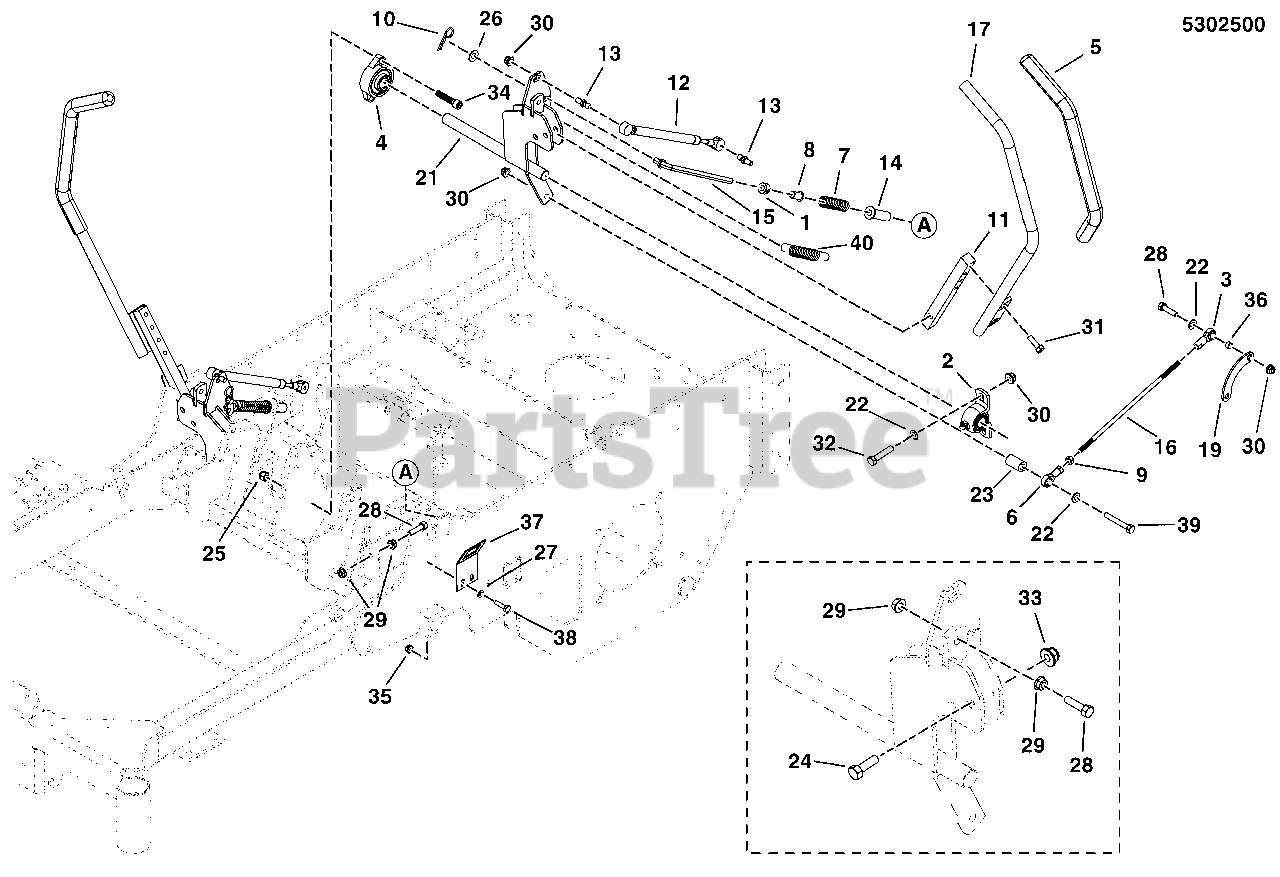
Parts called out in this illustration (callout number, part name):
1	COLLAR, 3/8" Set
2	BEARING, 3/4" PILLOW BLOCK
3	BALL JOINT 5/16-24 RH FEMALE STAMPED STL
4	BEARING, FLANGE
5	GRIP, FOAM, 3/4" ID, 16"" LONG
6	BALL JOINT 5/16-24 LH FEMALE STAMPED STL
7	SPRING, REVERSE RETURN
8	BUSHING, FLANGE 3/8ID X 7/8 LONG
9	NUT, Hex, 5/16-24
10	3/32 X 1-5/8 HAIR PIN CLIP
11	MOUNT, CONTROL ARM - BLK
12	DAMPENER, CONTROL,#(P6709/P3610)
13	BALL STUD, 5/16 X .50,# PC-477-2)
14	FLANGED BUSHING, 3/8IDX.63ODX.8125FL
15	ROD, NEUTRAL RETURN, CZ
16	ROD, HYDRO LINKAGE
17	WELD, HANDLE MOTION CONTROL LH - BLK
19	PLATE, HYDRO CONNECTOR - RED
21	WELD, CONTROL SHAFT, LH, SNP 2552 - BLK
22	WASHER, 5/16" SAE
23	SPACER, .38 X .75 X 1.25, YZ
24	BOLT, 3/8-16 X 1-3/4" GD5 YZ
25	NUT, Hex, Nylon Locking, 3/8-16
26	WASHER, 3/8 SAE
27	WASHER, 1/4 SAE
28	BOLT, 5/16-18 X 1-1/4" GD5 YZ
29	NUT, 5/16-18 HEX SERRATED FLANGE (SMALL)
30	NUT, 5/16-18 HEX NYLOCK FLANGE NUT
31	SCREW-HEX WSHR HD TAPTT5/16-18X0.750BLK
32	BOLT, 5/16-18 X 1" GRD5 YZ
33	NUT, 3/8 - 16 HEX NYLOCK FLANGE
34	BOLT, 3/8-16 X 1-3/4, SHCS, YZ
35	NUT, 1/4-20, GR5 Flanged Nylock, Zinc/Clear
36	SPACER, .328 X .425 X .250, CZ
37	SWITCH PLATE, MOTION CONTROLS - BLK
38	BOLT, 1/4-20 X 1" GD5 CZ
39	BOLT, 5/16-18 X 2-1/4" GD5 YZ
40	SPRING-EXT, .500 OD X 3.50 LG X .058 WR
